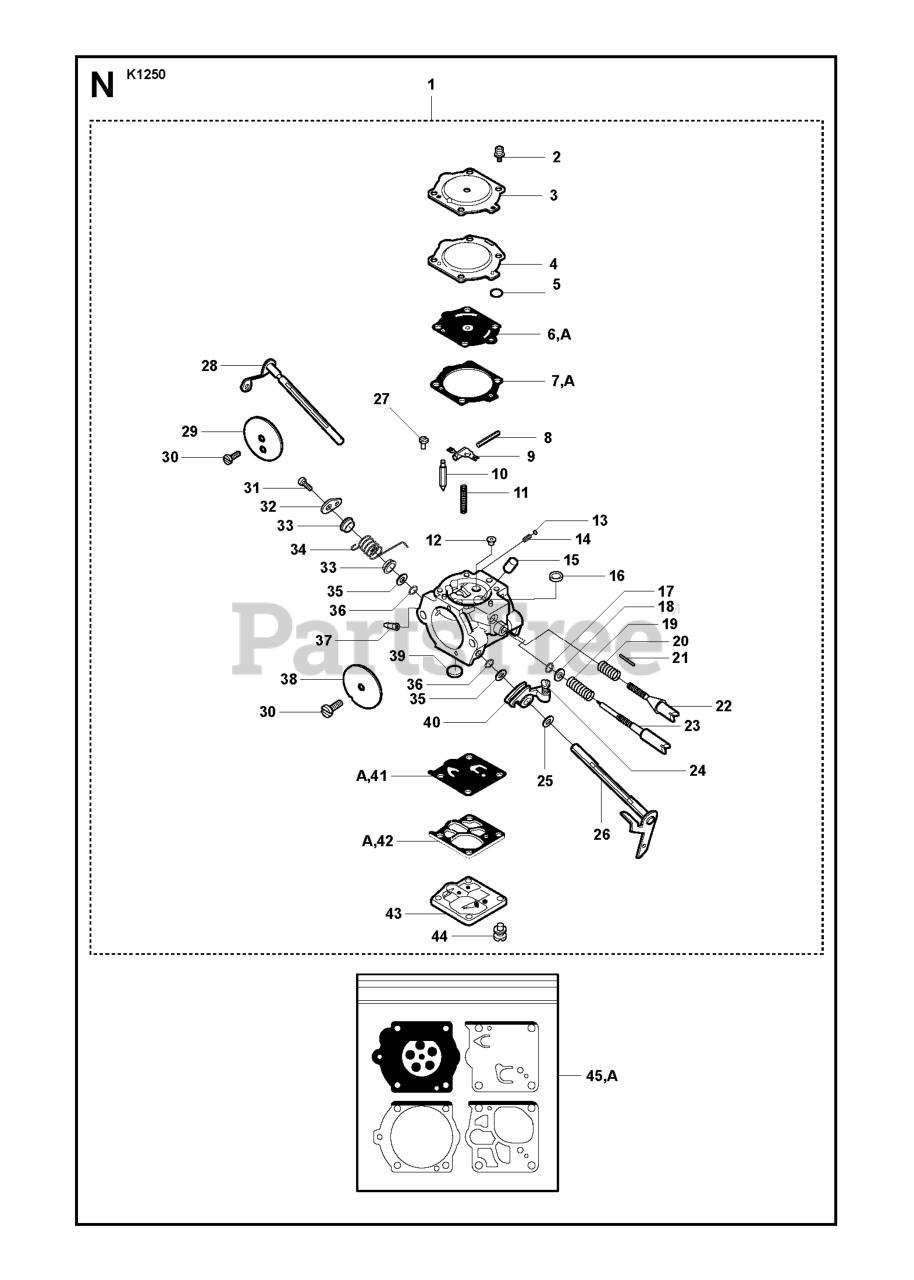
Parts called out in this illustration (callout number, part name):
1	CARBURETOR WGA WALBRO
3	COVER DIAPH
6	METERING DIAPHRAGM GSKT
10	INLET NEEDLE
11	LEVER SPRING
16	WELCH PLUG
19	PRESSURE SPRING
20	SPRING-MIX NEEDLE
21	ADJ NEEDLE-LO,CARB
22	ADJ SCREW-LO,CARB
23	HI-NEEDLE,CARB
26	THROTTLE SHAFT
29	CHOKE SHUTTER
30	SCREW SHUTTERS
34	SPRING,THROTTLE RETURN
37	FUEL NIPPLE-CARB
38	SHUTTER-THROTTLE
39	FUEL INLET SCREEN
41	DIAPHRAGM/PUMP
44	SCREW W/ WASHER
45	DIAPHRAM SET
